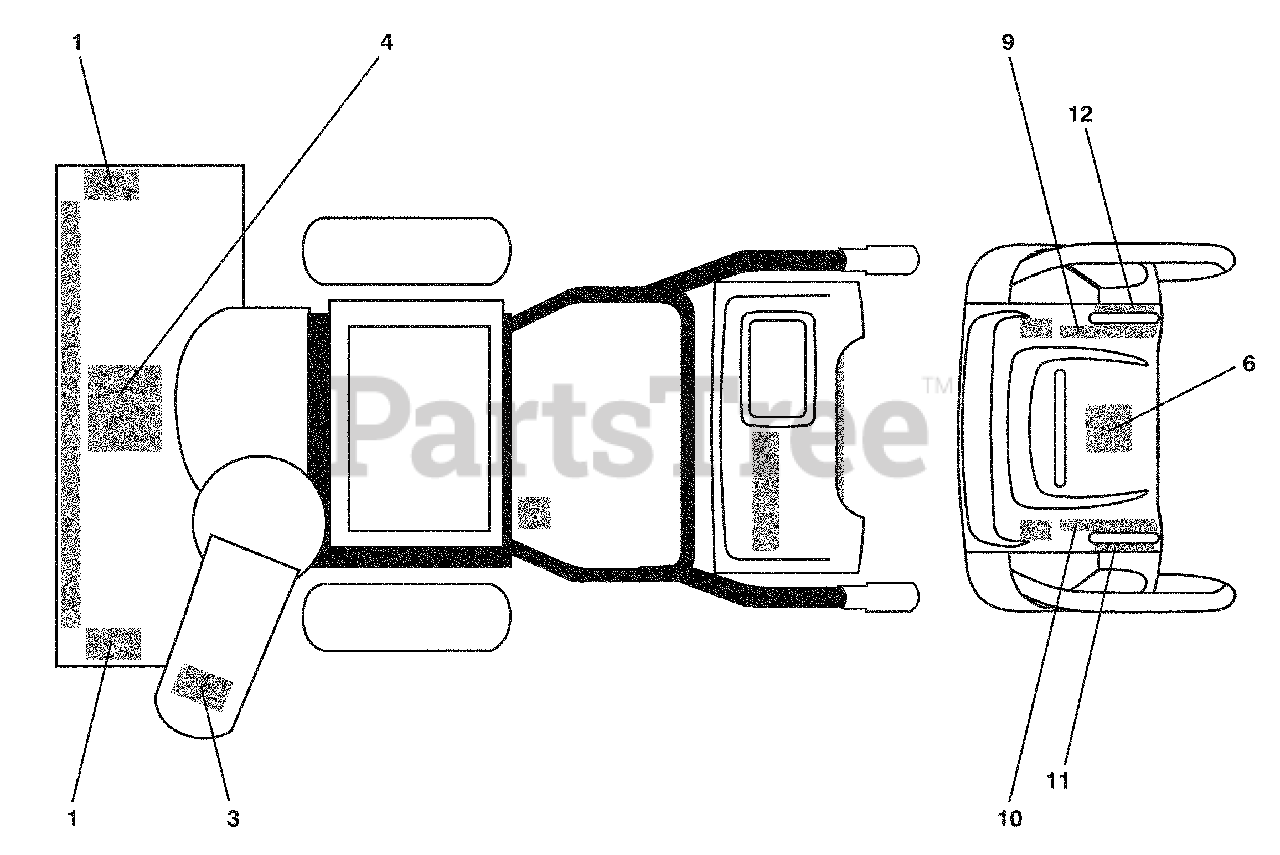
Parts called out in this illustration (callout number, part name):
1	DECAL, DANGER
3	DECAL, DANGER, DEFLECTOR
4	DECAL, DANGER
6	DECAL, INSTRUCTION
9	DECAL, SPEED CONTROL
10	DECAL, REMOTE DEFLECTOR
11	DECAL, LH TRIGGER
12	DECAL, RH TRIGGER
